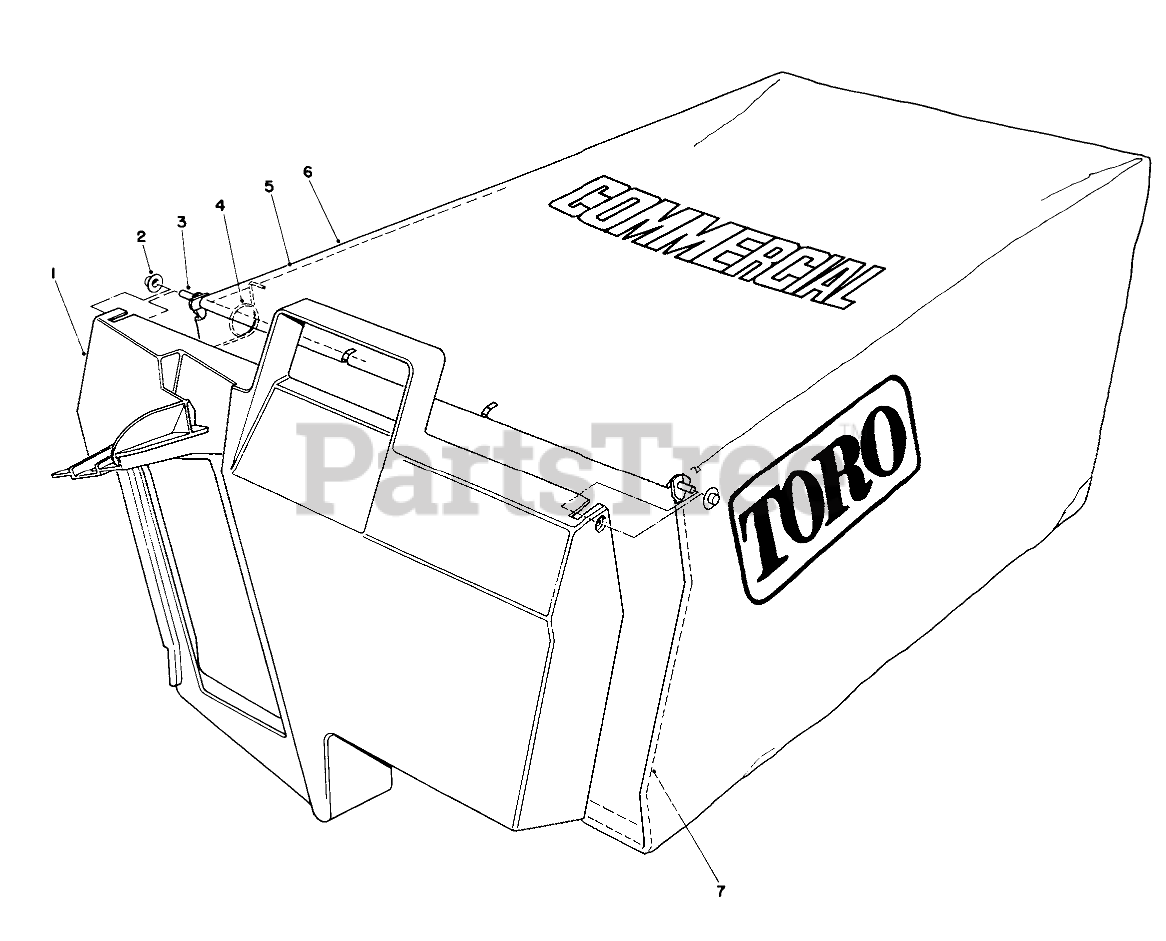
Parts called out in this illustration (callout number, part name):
1	DOOR-BAG, GRASS
2	NUT-PUSH
3	HINGE-DOOR, BAG
4	SPRING
5	FRAME-BAG, UPPER
6	Bag
7	FRAME-BAG
